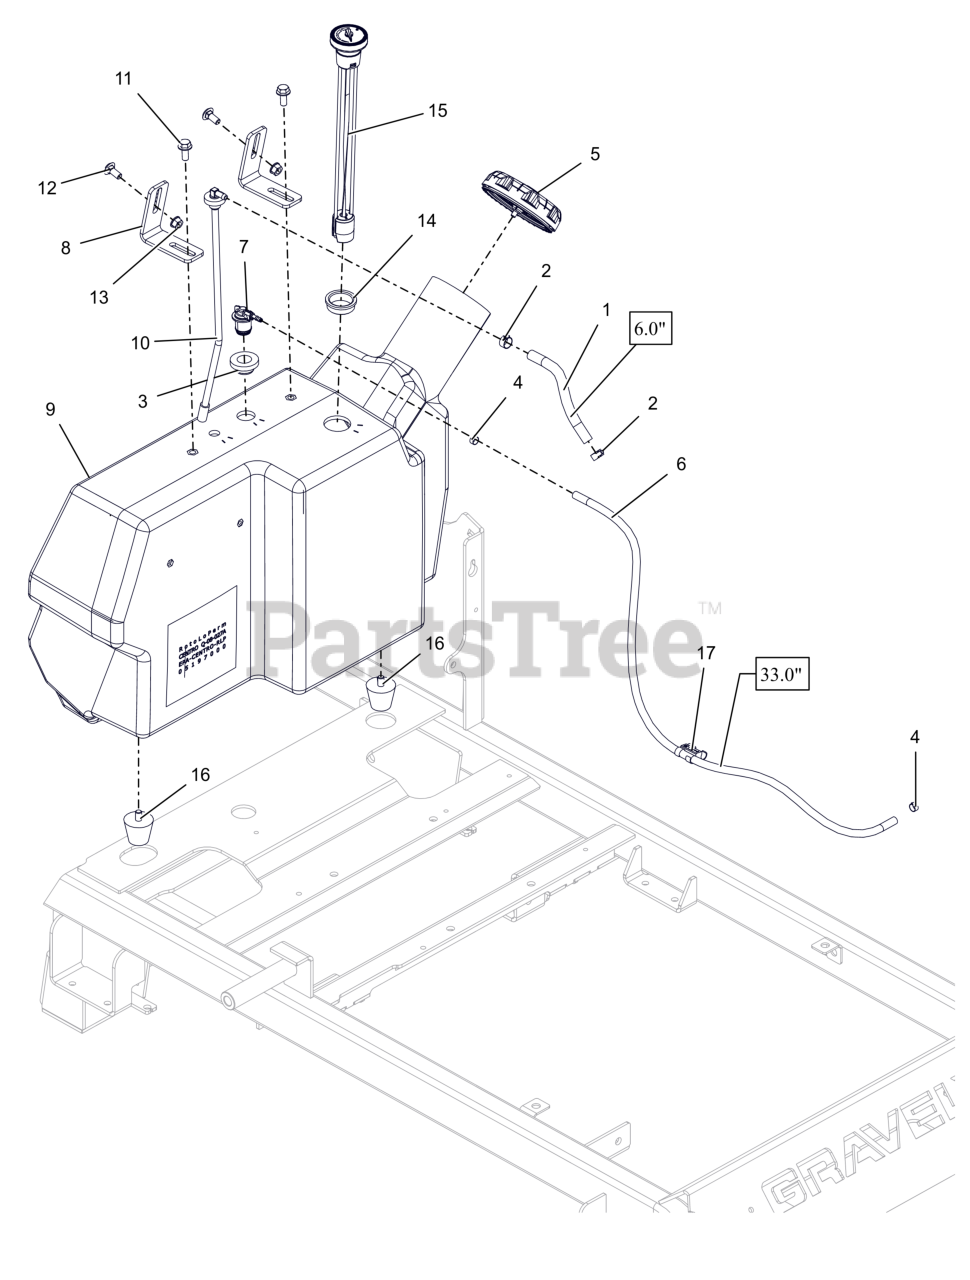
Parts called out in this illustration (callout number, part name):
1	HOSE, .25 LOW-PERM BULK GAS
2	CLAMP, FUEL LINE
3	GROMMET, REMOTE VENT NITRILE
4	CLAMP-HOSE, SPRING .188
5	CAP, FUEL VENTIN AUTOLOCK
6	HOSE, .188 30R7 BULK
7	VALVE, COMBINATION VENT 3/16
8	BRKT, TANK HOLDDOWN
9	ASSY,48-60 PROSTANCE FUEL TANK
10	ASM, PROSTANCE FUEL LINE PICK-UP
11	BLT, SERHFWH 0.312-18X0.75 GR5 ZCC
12	BLT,RHSN .31-18X.75 G5 ZCC
13	NUT,LK-CTR-FLG .31-18 GF ZCC
14	GROMMET, FUEL GAUGE
15	GAUGE, REMOTE FUEL SEALED 12"
16	BUMPER, STUD MOUNTED CONE SHAPED
17	CLIP, T, .38-.50
